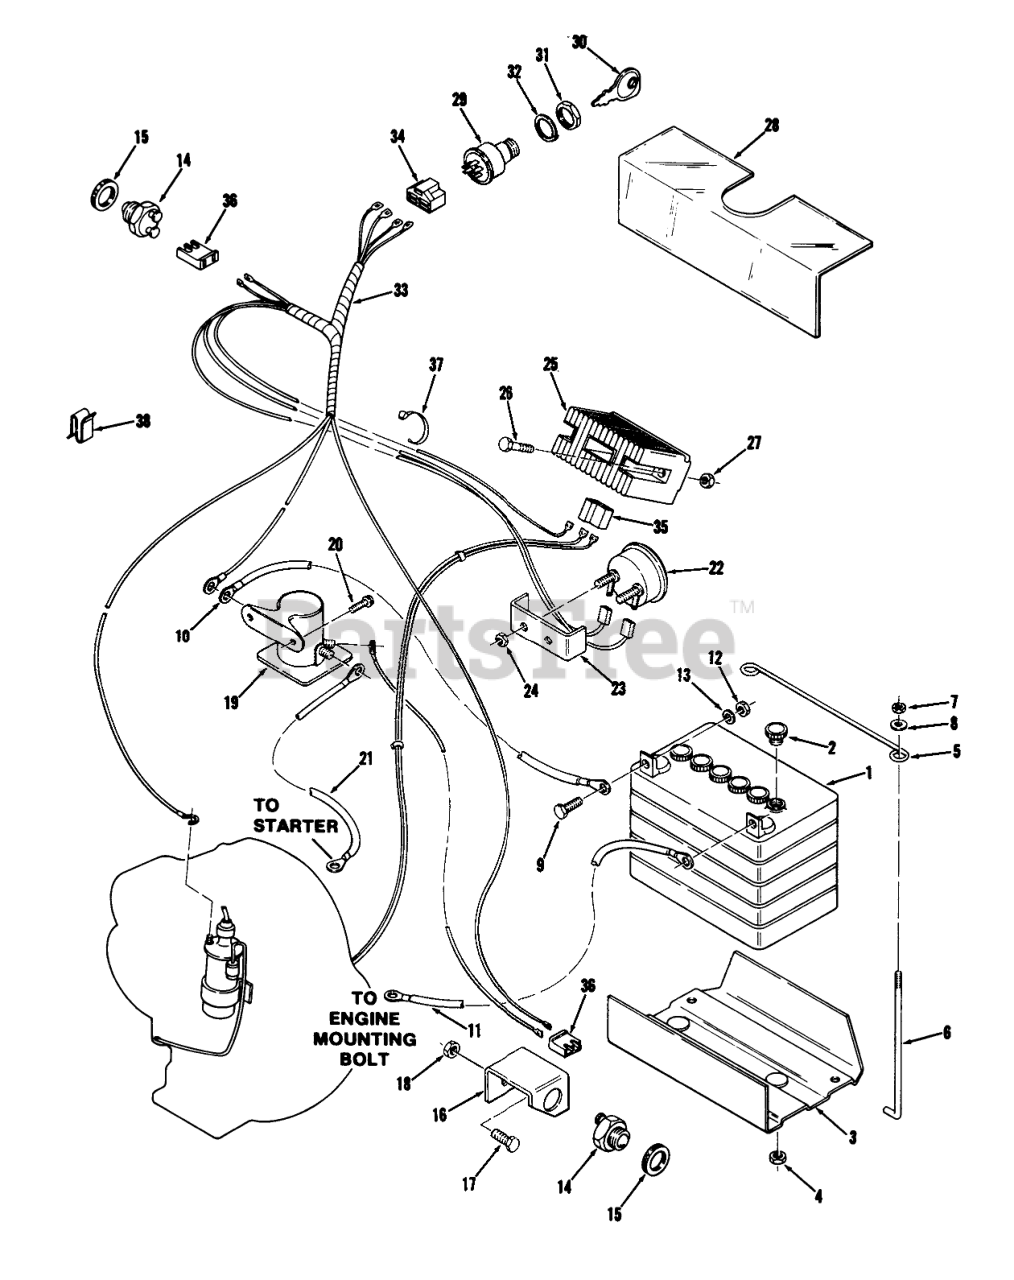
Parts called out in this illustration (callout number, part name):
1	Battery
3	Battery Box
4	Nut
5	ROD-HOLD DOWN
6	Hook
7	Nut
9	Bolt
10	Wire Assembly
11	Wire
12	Nut
14	SWITCH-INTERLOK CLUT
15	NUT-SPECIAL 9/16-18
16	Bracket
17	BOLT
18	Nut
19	Solenoid
20	Screw
21	Wire
22	AMMETER W/CLAMP
23	Clamp
24	HEX NUT 10-32 E.S.
25	REGULATOR-RECTIFIER
26	Bolt
27	Nut
28	CONTROL PROTECTOR
29	SWITCH-IGNITION
30	Key-EL
32	LOCKWASHER
33	WIRING HARNESS & DIA
34	CONNECTOR-5 WAY-SERV
35	CONNECTOR
36	Connector Housing Pedal Switch
37	PLASTIC TIE
37	Cable Tie
38	SPEED CLIP
